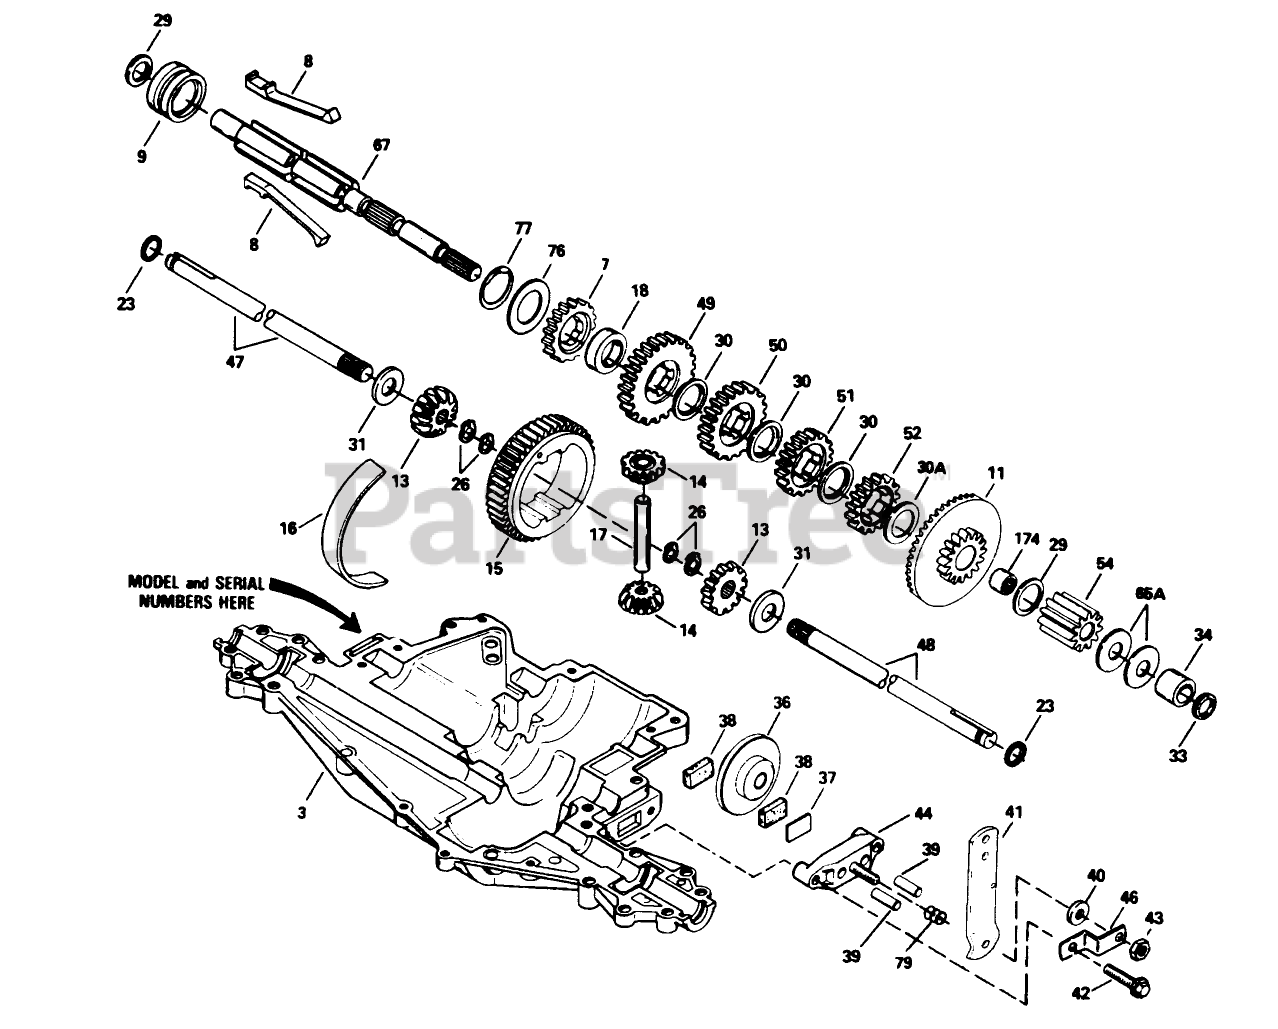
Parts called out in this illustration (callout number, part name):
3	Transaxle Case
7	Gear-Spur (22 teeth)
8	Shift Key
9	Shift Collar
11	Bevel Gear Bearing (44/16 Teeth) (Incl. Ref. #174)
13	Gear Bevel
14	Gear Pinion
15	Gear-Ring
16	Bearing Strip
17	Drive Pin
18	Neutral Spacer
23	Ring-Seal
26	Retaining Ring (pkg of 2)
29	Washer
30	Washer
30A	Washer
31	Washer
33	O-Ring
34	Bushing
36	Brake Disk
37	Brake Pad Plate
38	Brake Pad
39	Dowel Pin
40	Washer
41	Brake Lever
42	Ring Set (.020 O S)
43	Locknut
44	Nozzle-Carburetor
46	Bracket
47	Axle (16-13/16" Ig.)
48	Axle (11-5/8" long)
49	Gear-Spur, 35 Teeth
50	Gear-Spur 27 Teeth
51	Spur Gear (19 Teeth)
52	Gear-Spur 20 teeth
54	Spur Gear (11 Teeth)
65A	Washer
67	Shifter Brake Shaft
76	Washer
77	Inverted Retaining Ring
79	Piston ASM (.020 O S)
174	Needle Bearing
